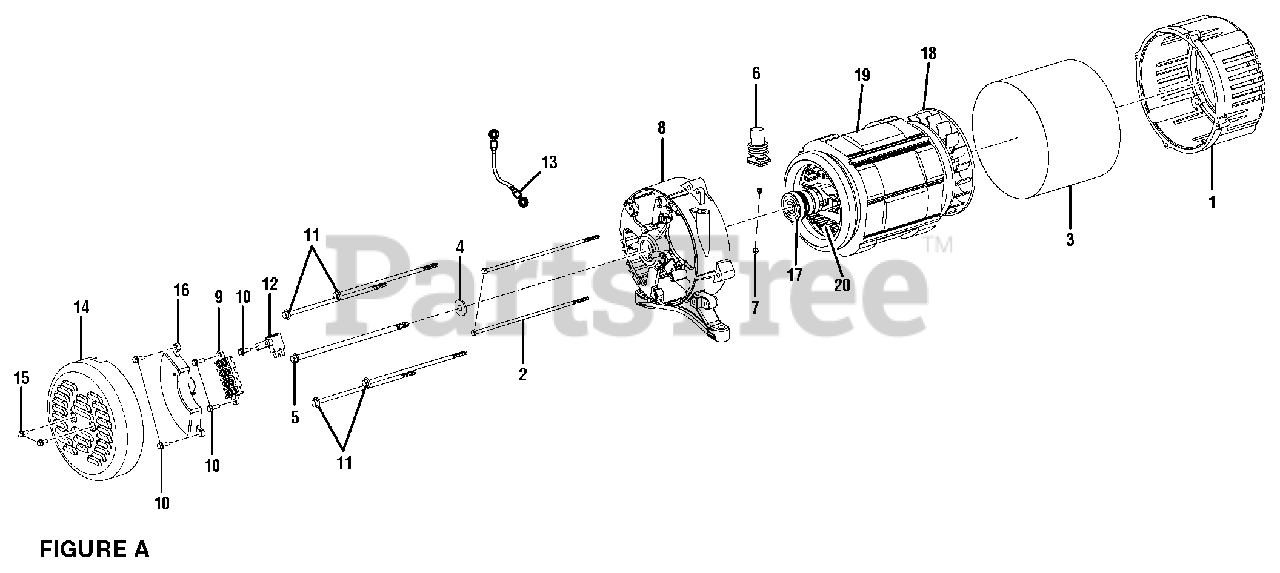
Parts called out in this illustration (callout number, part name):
1	Adaptor Housing
2	Bolt (M5 x 230, Hex Hd.)
3	Generator Head Cover
4	Lock Washer (5/16 in.)
5	Rotor Bolt (170 mm)
6	Rubber Boot
7	Hex Nut (M5)
8	Bearing Housing
9	Terminal Block
10	Bolt (M5 x 16 mm)
11	Stator Bolt (170 mm)
12	Brush Assembly
13	Bonding Wire
14	Brush Cover
15	Bolt (M5 x 12 mm)
16	Automatic Voltage Regulator
